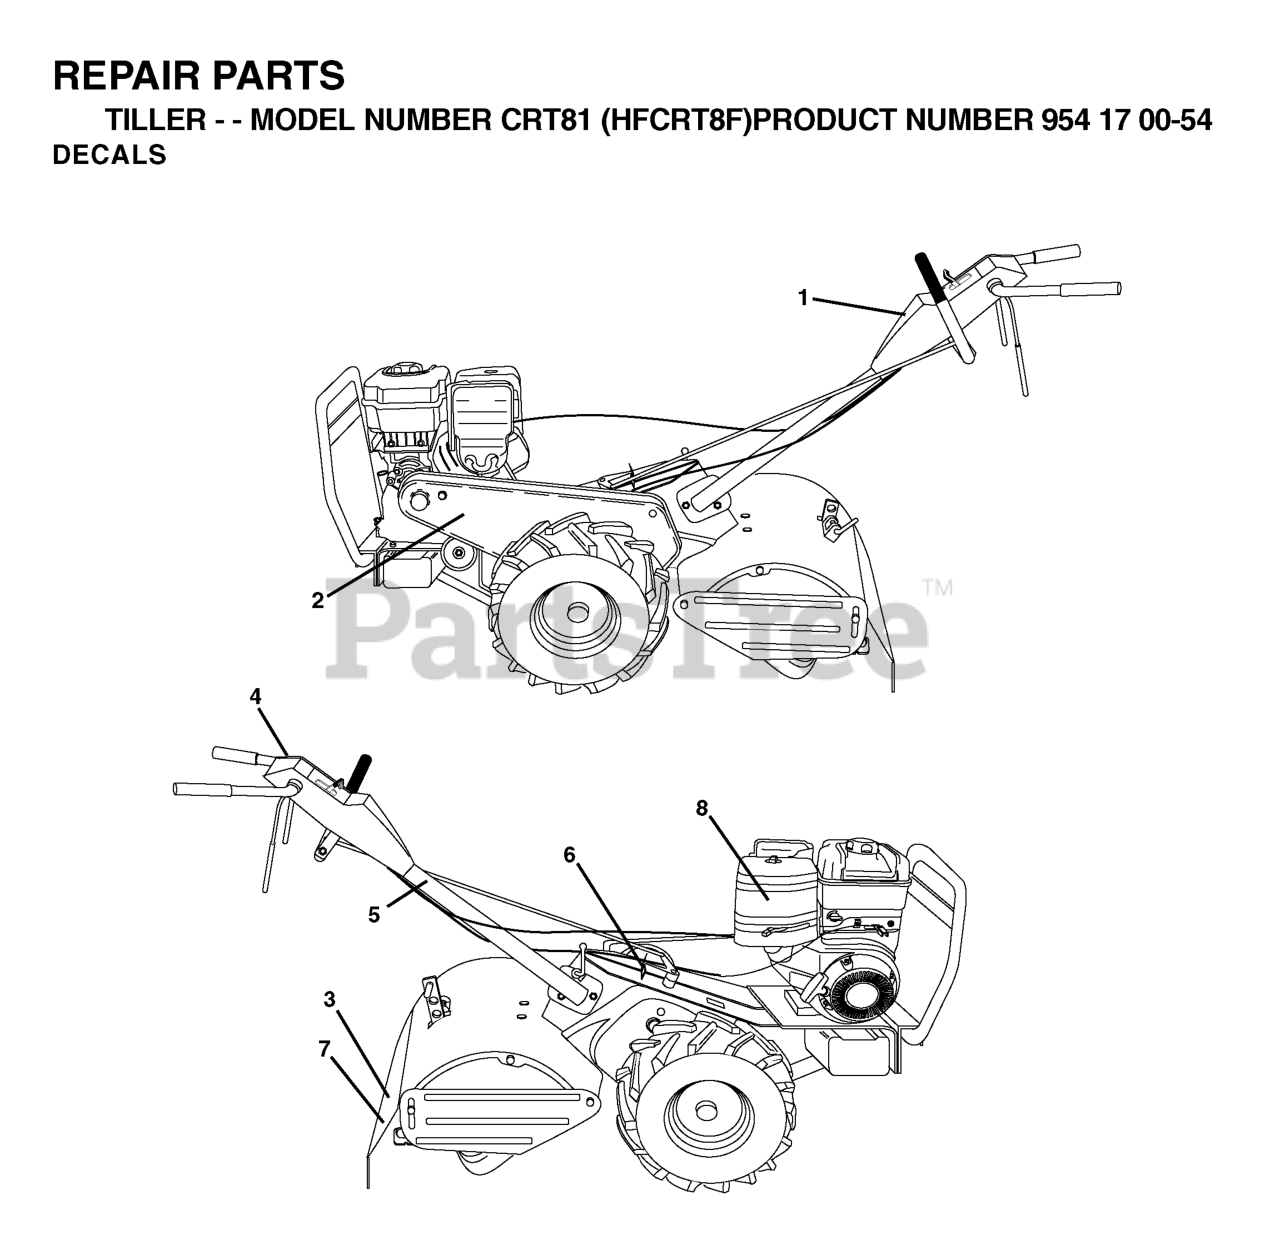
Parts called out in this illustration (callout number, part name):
1	DECAL, LOGO
3	DECAL EUROPE STANDARD CE
5	DECAL.PLACEMENT.HAND.SYMBOLS
6	DECAL, SHIFT INDICATOR
7	DECAL.WARNING.4-SYM.TILLER.INT
